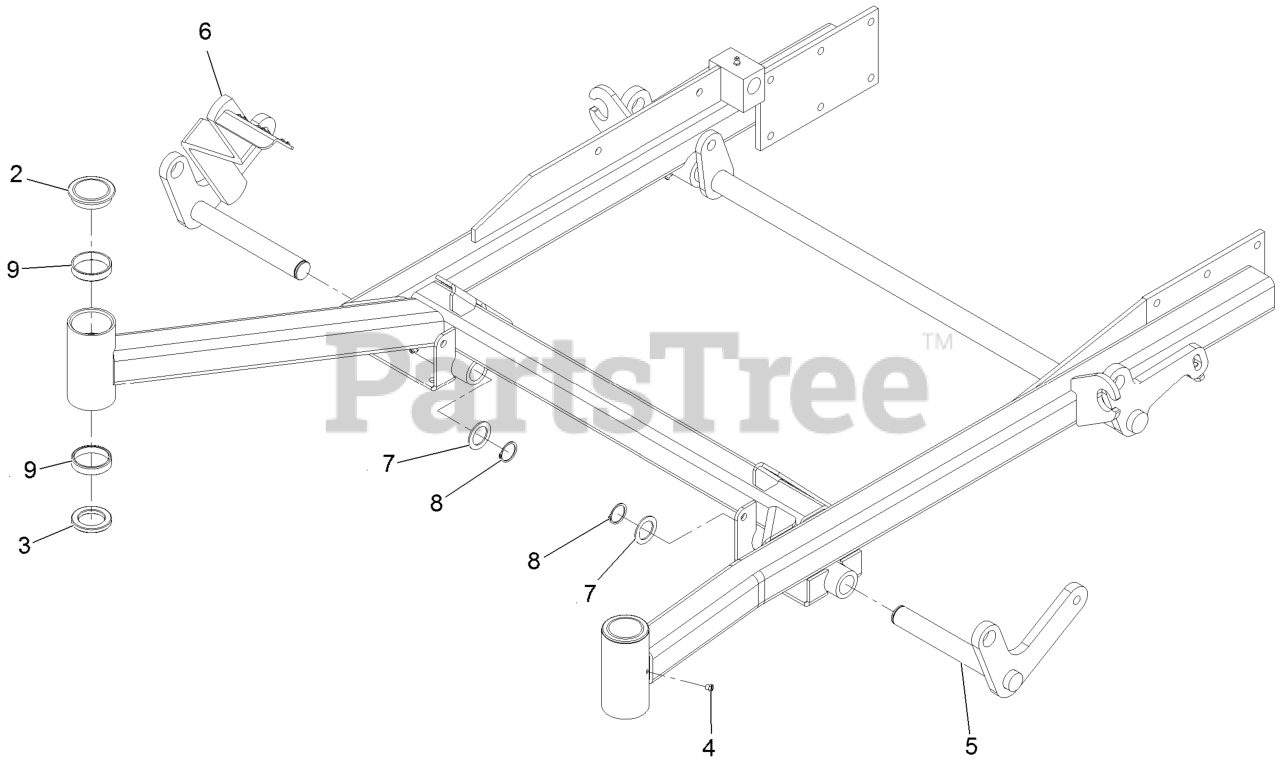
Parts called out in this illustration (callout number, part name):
2	CAP-GREASE
3	SEAL-GREASE
5	WLD,FRONT LIFT SHAFT-LH
6	WLD,FRONT LIFT W/LEVER
7	WASHER-SPACER
8	RING-RETAINING
9	CUP-BEARING
